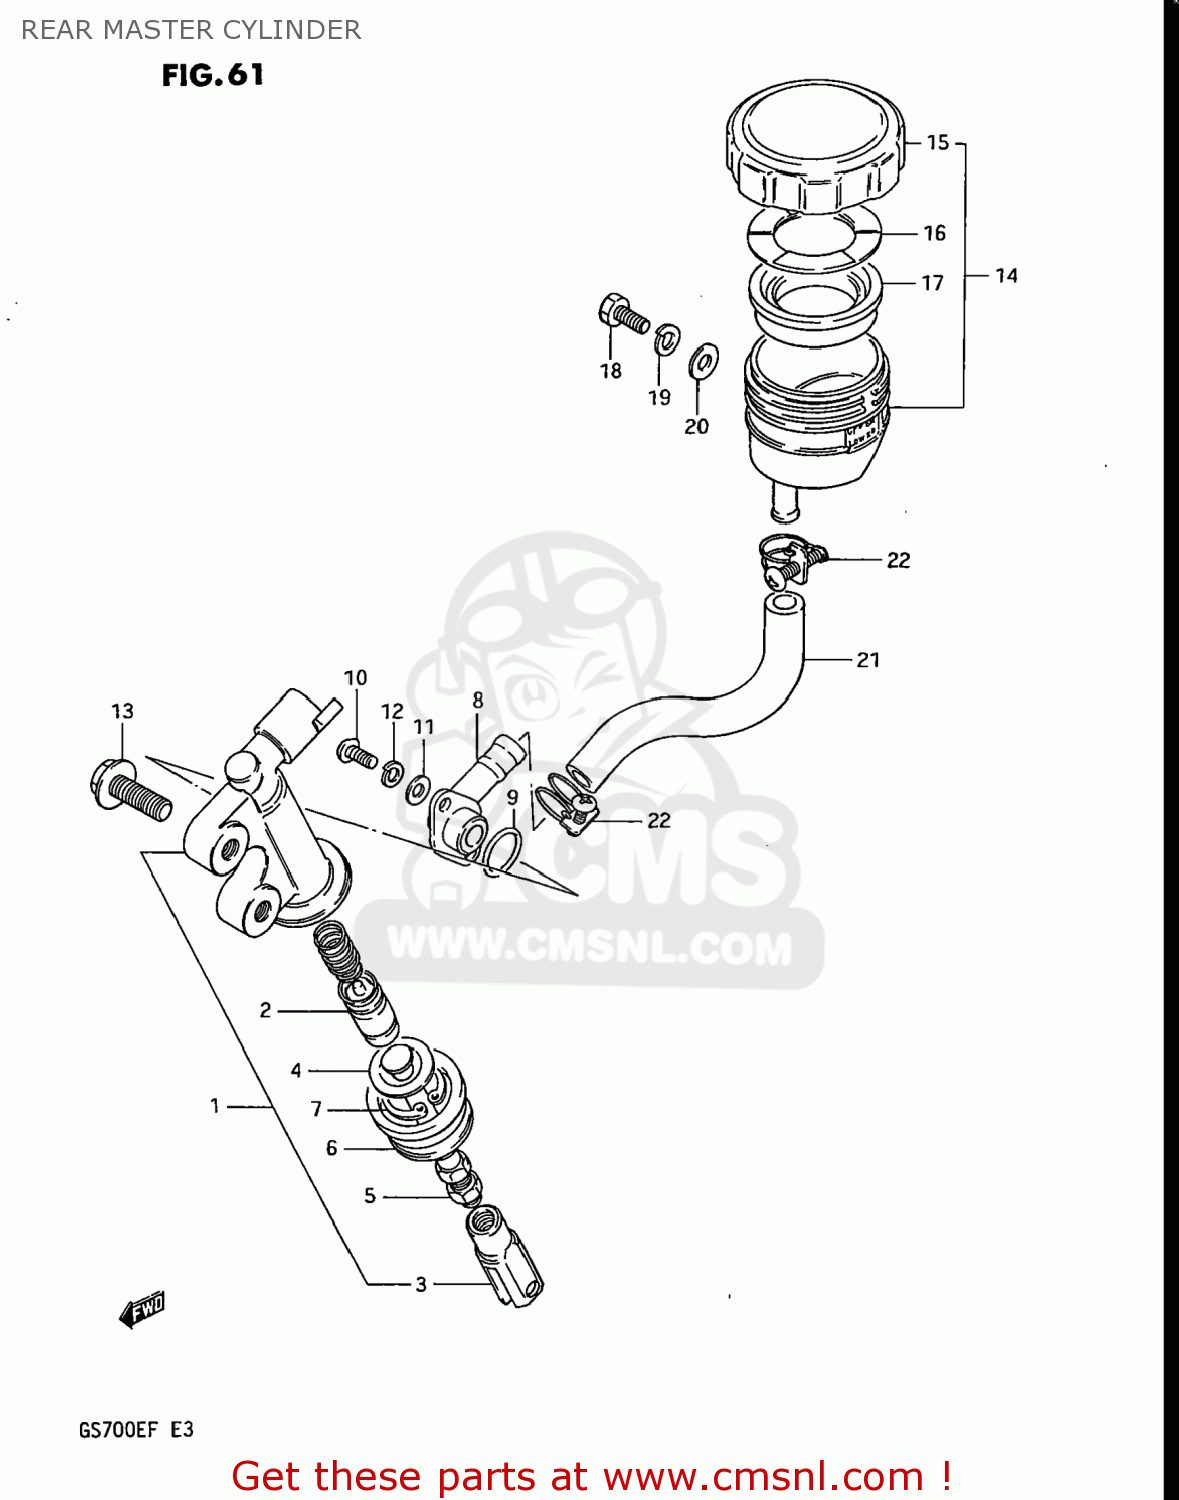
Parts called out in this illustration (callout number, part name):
1	CYLINDER ASSY,RR MASTER
2	PISTON/CUP SET
3	YOKE
4	ROD,PUSH
5	NUT,MASTER CYLINDER
6	BOOT
7	CIRCLIP
8	CONNECTOR,HOSE
9	O RING
10	SCREW
11	WASHER
12	LOCK WASHER
13	BOLT
14	TANK ASSEMBLY,RESERVOIR
15	CAP
16	PLATE,DIAPHRAGM
17	DIAPHRAGM
18	SCREW(6X12)
19	LOCK WASHER
20	WASHER
21	HOSE,RESERVOIR TANK
22	CLAMP
